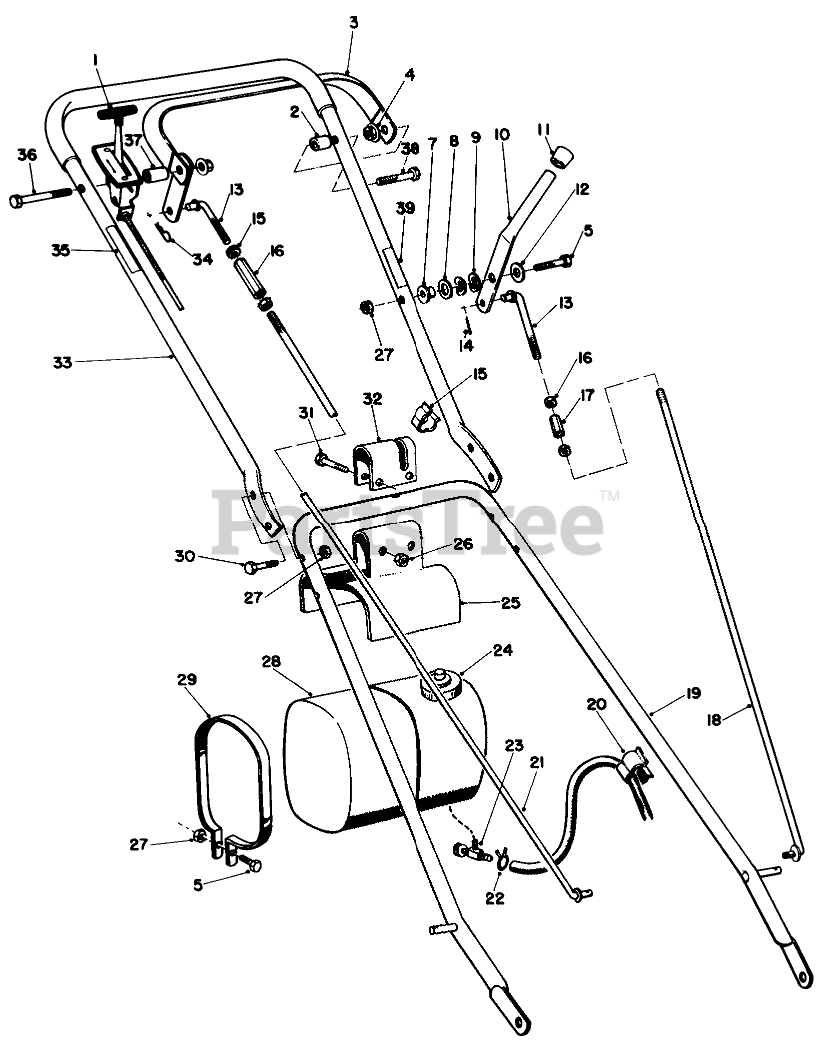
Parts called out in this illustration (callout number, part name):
1	Control, Throttle
2	Spacer
3	Control Bail
4	NUT-LOCK, HHF
5	SCREW-HH
7	PIVOT
8	WASHER-FLAT
9	WASHER-SPRING
10	CUTTER HANDLE R
11	Button Plug
12	WASHER-FLAT
13	LINK CONTROL ROD
14	PIN-COTTER
15	Clamp
16	NUT-KEPS
17	CONTROL ROD SLEEVE
18	CUTTER CONTROL ROD
19	LOWER HANDLE WA
20	CLAMP
21	CONTROL ROD
22	Clamp
23	.125 ID SHUTOFF VALVE
25	FUEL TANK BRACKET
26	Nut
27	NUT-LOCK
28	Tank
29	TANK STRAP
30	SCREW-HH
31	SCREW-HH
32	Clamp
33	Upper Handle
34	PIN-COTTER
35	Decal-Throttle
36	SCREW-HH
37	SLEEVE-PIVOT ROLLED
38	SCREW-HH
39	BLADE CONTROL DECAL
